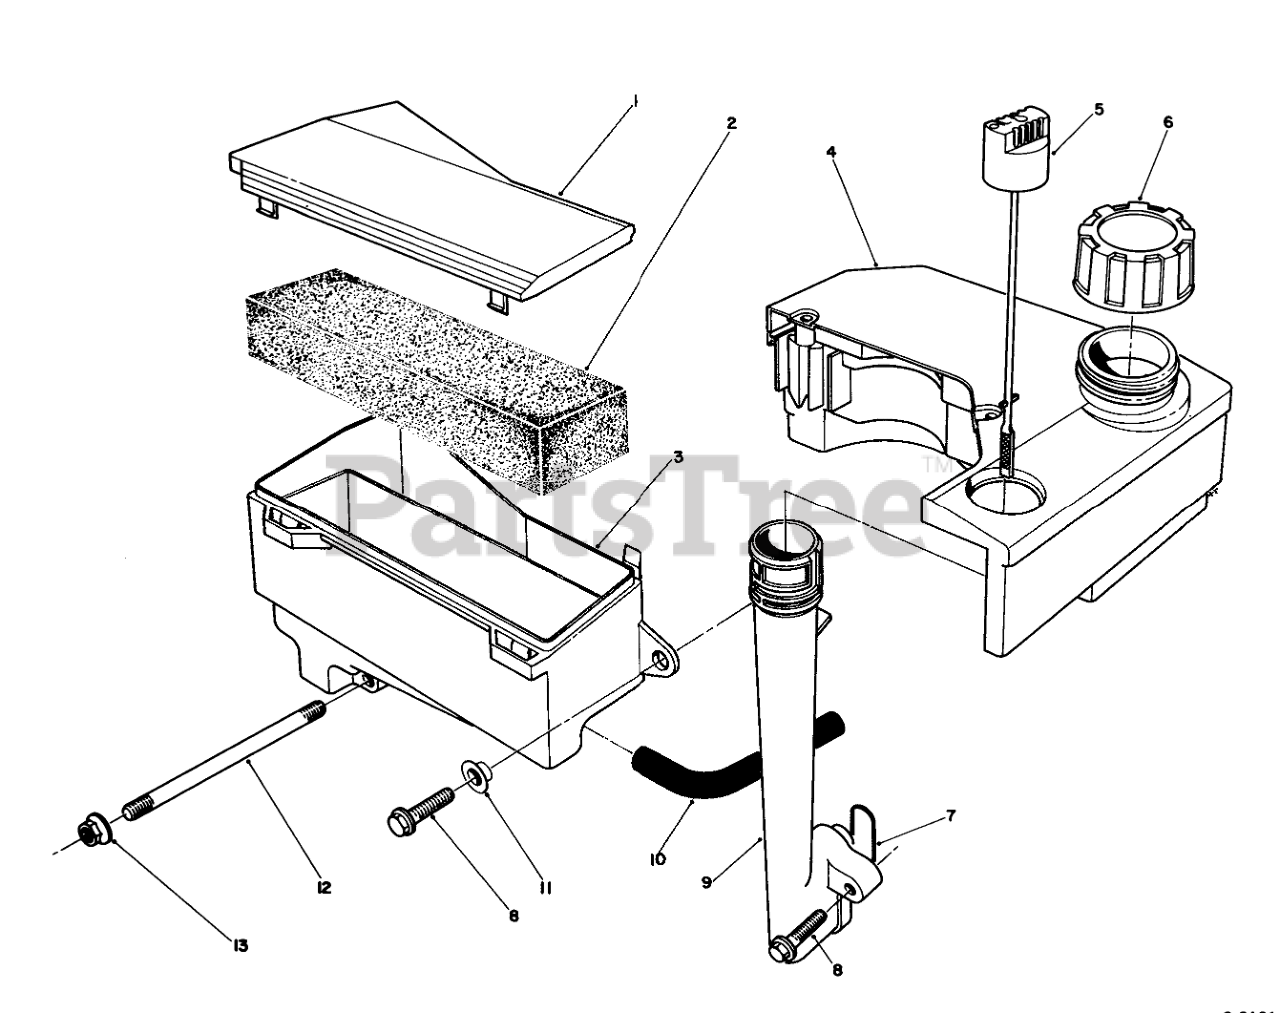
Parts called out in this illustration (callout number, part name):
1	AIR CLEANER CAP
3	Body-Air Cleaner
4	TANK ASM
5	Dipstick
6	GAS CAP ASM
7	0-Ring-Oil Tube
11	SPACER
12	Stud-Carburetor
